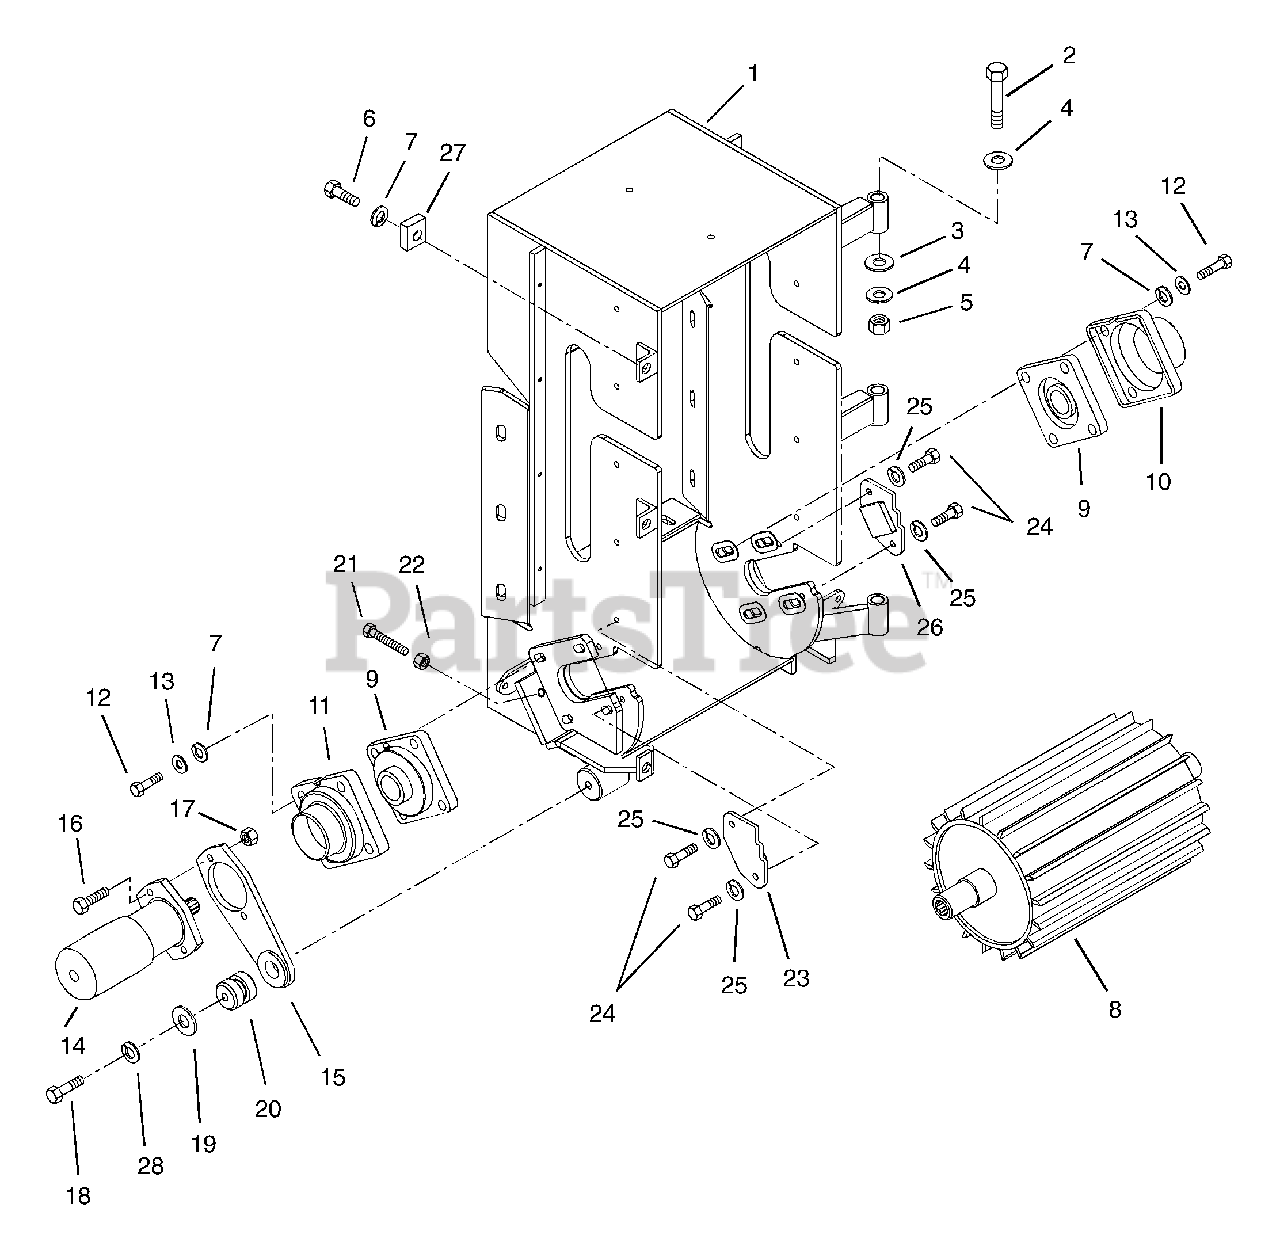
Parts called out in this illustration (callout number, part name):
1	Feed Box Replacement
1	Feed Box Weldment Assembly
2	Bolt-Hex .75-10 x 5.50 Grade 5
3	Washer-Hardened-Thrust .758 x 1.23 x .031
4	Washer-Flat-Steel .812 x 1.50 x .139
5	Nut-Locking-Center .75-10
6	Bolt-Hex .50-13 x 1.75 Grade 5
7	Washer-Lock .50 x .125
8	Roller Weldment-Bottom
9	Bearing-Flange 4-Bolt 1.625
10	Cover Bearing
11	Cover Shaft
12	Bolt-Hex .50-13 x 1.75
13	Washer-Flat-Steel .531 x 1.06 x .095
14	Motor-Hydraulic
15	Torque Arm Weldment
15	Torque Arm Weldment Assembly
16	Bolt-Hex .50-13 x 1.50 Grade 5
17	Nut-Locking-Center .50-13
18	Bolt-Hex .50-13 x 3.00 Grade 5
18	Bolt-Hex .625-11 x 4.00 Grade 8
19	Washer-Flat-Steel .50 x 2.25 x .13
19	Washer-Flat-Steel .656 x 2.25 x .184
20	Rubber Bushing
20	Bushing-Isolation
21	Bolt-Hex .50-13 x 2.25
22	Nut-Hex .50-13
23	Plate-Roller Slot Cover RH Weldment
24	Bolt-Hex .38-16 x .75 Grade 5
25	Washer-Lock .38 x .094
26	Plate-Roller Slot Cover LH Weldment
27	Block-Clamp
28	Washer-Locking .50 x .125
28	Washer-Locking .62 x .156
